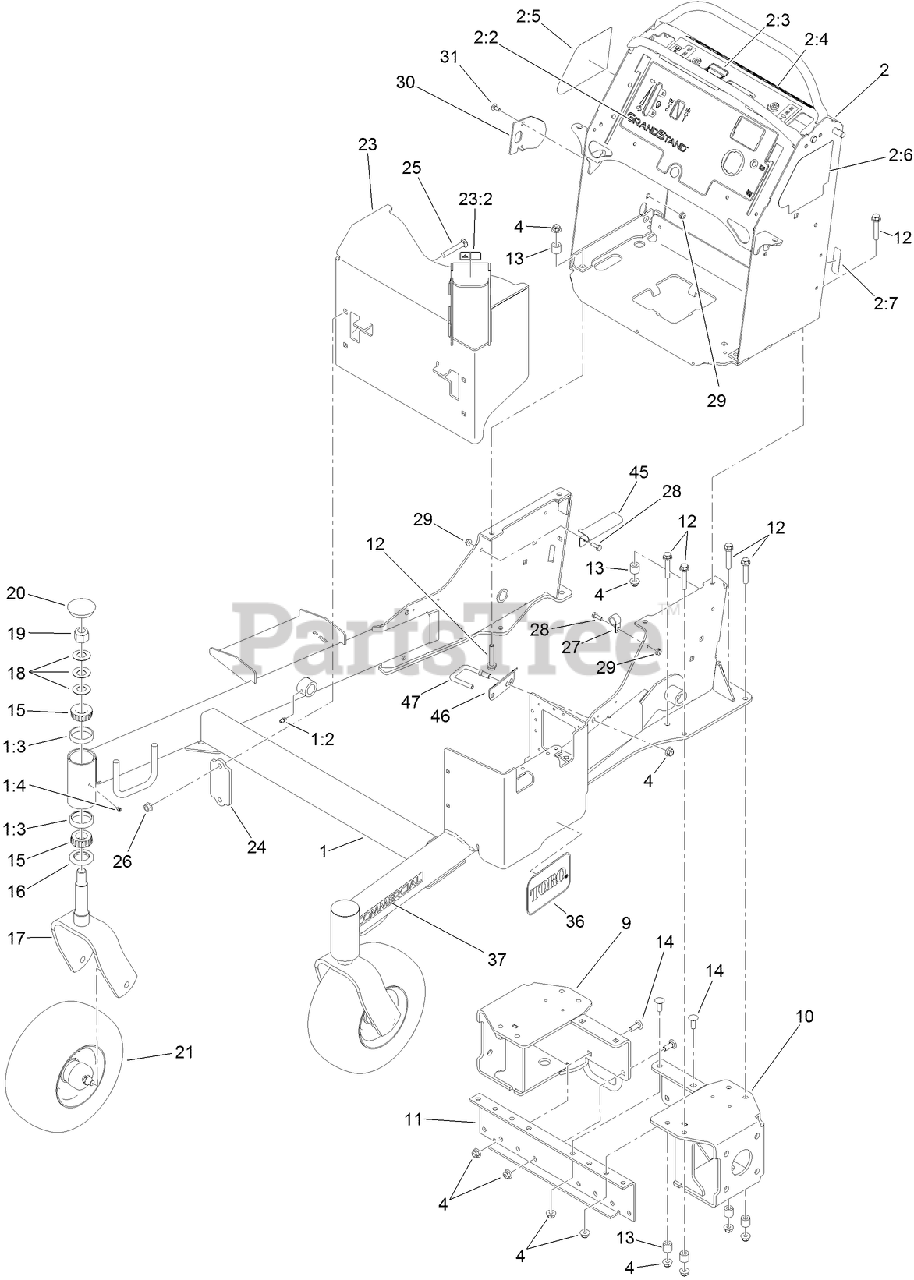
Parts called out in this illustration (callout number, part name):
1	FRONT FRAME ASM
1:2	FITTING-GREASE
1:3	CUP-BEARING
2	CONTROL TOWER ASM
2:2	DECAL-PANEL, CONTROL
2:3	DECAL-OPC
2:4	DECAL-WARNING
2:5	DECAL-HOC
2:6	DECAL-SERVICE/SPARK ARREST
2:7	DECAL-FUSE
4	NUT-HF, NI
9	MOUNT-MOTOR, RH
10	MOUNT-MOTOR, LH
11	MOUNT-MOTOR, CENTER
12	SCREW-HHF
13	SPACER
14	SCREW-CARR
15	BEARING-ROLLER, TAPERED
16	SEAL-GREASE
17	FORK-CASTER
18	WASHER-BELLVILLE
19	NUT-LOCK, NI
20	CAP-GREASE
21	WHEEL/TIRE AND BEARING ASM
23	MUFFLER GUARD ASM
23:2	DECAL-WARNING
24	BRACKET-MOUNTING, GUARD
25	SCREW-CARR
26	NUT-HF
27	CLAMP-CABLE
28	SCREW-HH
29	NUT-HF
30	PLATE-STRIKER
31	SCREW-CARR
36	DECAL
37	DECAL-COMMERCIAL
45	BRACKET-HOSE, FUEL (DOUBLE)
46	GUARD-HOSE
47	GUIDE-HOSE
